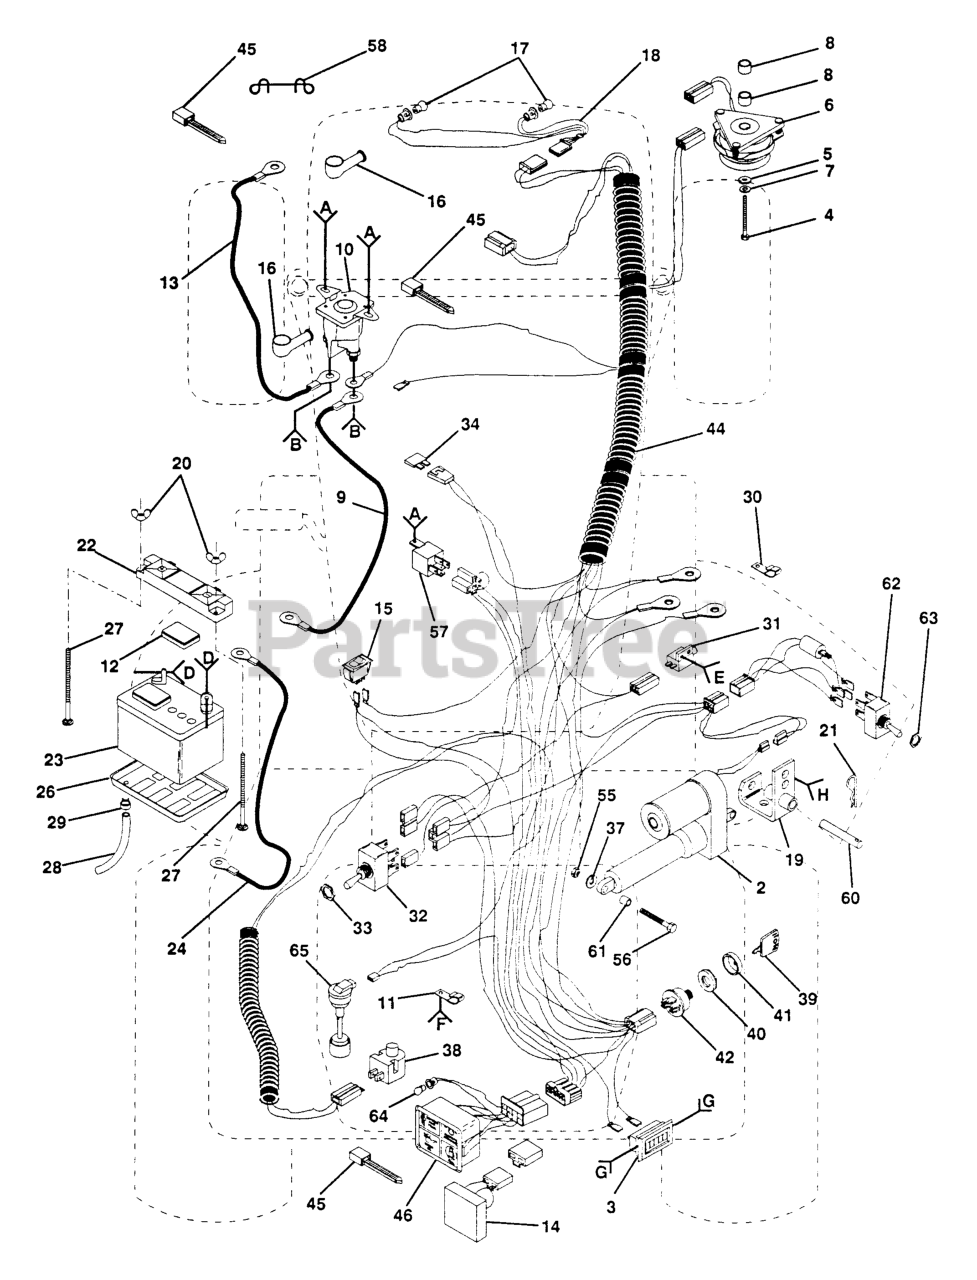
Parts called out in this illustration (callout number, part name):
2	ELECT ACTUATOR
3	HOUR METER T
4	Bolt, Hex 7/16-20 x 1-1/2 Grade 8
6	ELECTRIC CLUTCH T
7	LOCKWASHER
8	SPACER-CLUTCH GT
9	CABLE-BATTERY YTV
10	SOLENOID KIT
11	CLIP T
12	CAP BATTERY NLA
13	STARTER CABLE GT
14	SENSOR LOW VOLTAGE
16	TERMINAL COVER
17	BULB-LIGHT T
20	WING NUT
22	TERMINAL GRD YTV
23	BATTERY
24	CABLE T
26	BATTERY TRAY T
28	BATT DRAIN TUBE T
29	HOSE CLAMP T
31	SWITCH-INTER. GT
32	SWITCH,PTO
33	HEX NUT T
34	FUSE *
37	WASHER, LOCK 3/8
38	RP.SWITCH.PLUNGER.NC.GRAY
39	KEY.MOLDED.GENERIC
40	NUT
41	BEZEL.SWITCH.IGNITION
42	SWITCH
44	HARNESS IGNITION
45	TIE GUIDE
46	LIGHT PACKAGE
55	NUT.HEX.3/8-16UNC
56	BOLT-HEX EAK
57	RELAY.ASSY.T
60	PIN-ACTUATOR T
62	LIFT,SW WIRING
63	LOCKWASHER
64	BULB LIGHT T
65	SENSOR, LOW FUEL
